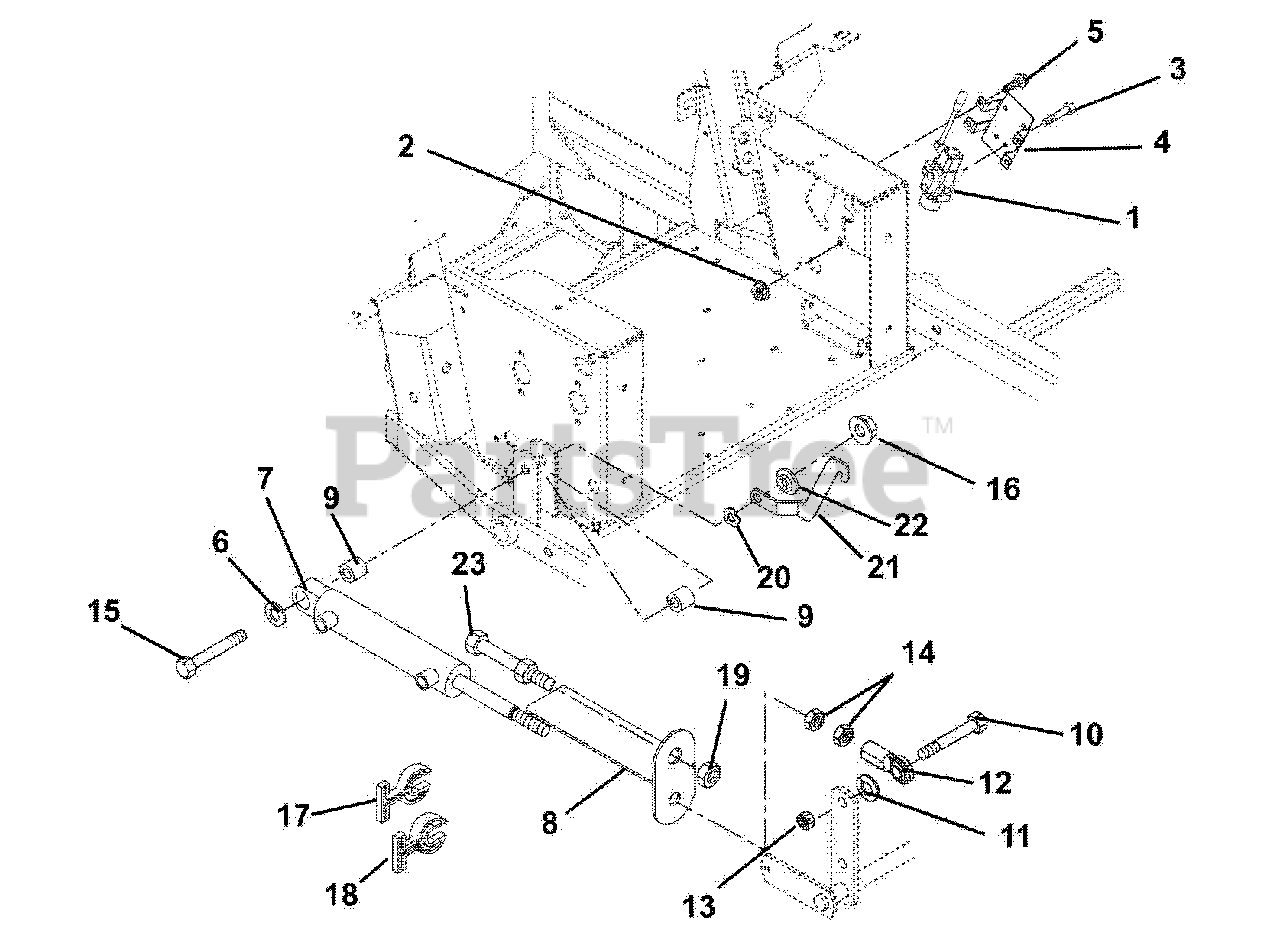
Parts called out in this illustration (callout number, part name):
1	Valve, Hydraulic
2	Nut, Locking Top Flange .31-18
3	Bolt, Hex .31-18 x 2.50 Grade 5
4	Bracket, Valve Mounting
5	Screw-Tapping .38-16 x .50 Hex Washer Head
6	Washer-Flat-Steel .515 x 1.625 x .25
7	Cylinder-Lift
8	Strap-Height of Cut Indicator
9	Bushing .516 x 1.00 x 1.05
10	Bolt-Hex .62-11 x 2.25 Grade 8
11	Washer-Lock .62 x .156
12	Rod End-Right Hand-Female .625
13	Nut-Locking-Center .62-11
14	Nut-Jam .625-18
15	Bolt-Hex .50-13 x 3.75 Grade 5
16	Nut, Locking Top Flange .50-13
17	Stop, Cylinder .34 Thick
18	Stop, Cylinder .68 Thick
19	Nut, Jam .75-16
20	Washer, Wave .076 x 1.12 x .08
21	Latch, Floor Board
22	Bushing-Flange .515 x .75 x .275 x 1.12
